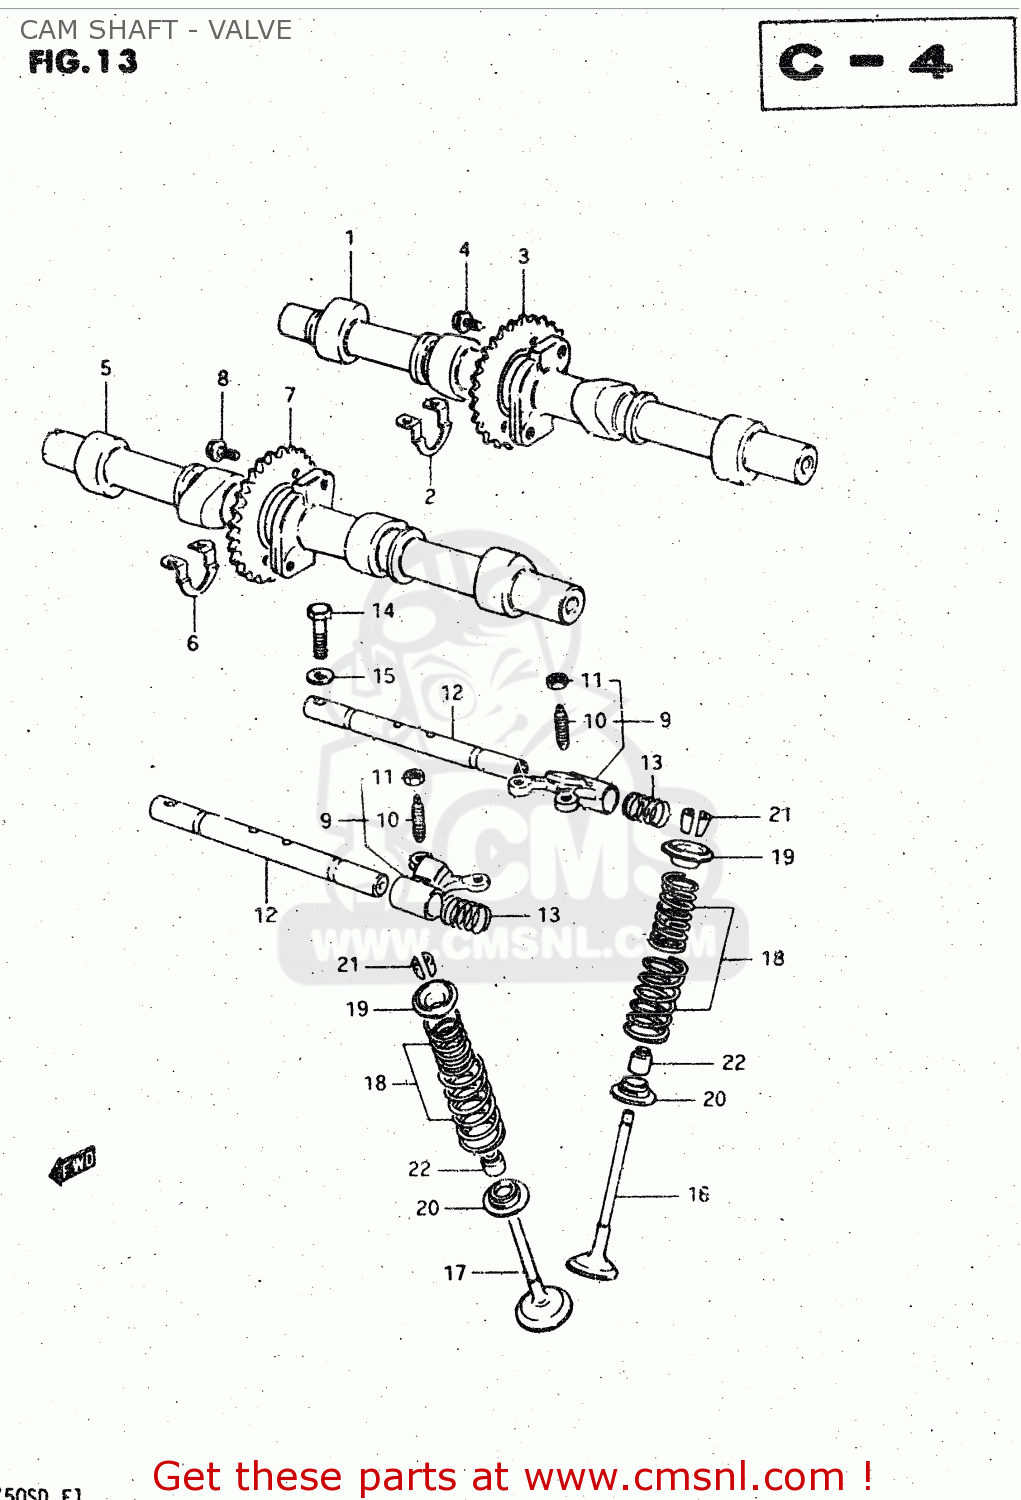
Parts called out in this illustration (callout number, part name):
1	CAMSHAFT SET,INTAKE
2	SHIM,CAMSHAFT
3	SPROCKET,INTAKE CAMSHAFT
4	BOLT(7X11)
5	CAMSHAFT SET,EXHAUST
6	SHIM,CAMSHAFT
7	SPROCKET,EXHAUST CAMSHAFT
8	BOLT(7X11)
9	ARM,VALVE ROCKER
10	SCREW,TAPPET ADJUSTING
11	NUT,ADJUSTING
12	SHAFT,VALVE ROCKER
13	SPRING
14	BOLT
15	WASHER
16	VALVE,INTAKE
17	VALVE,EXHAUST
18	SPRING SET,VALVE
19	RETAINER,VALVE SPRING
20	SEAT,VALVE SPRING
21	COTTER, VALVE
22	OIL SEAL
